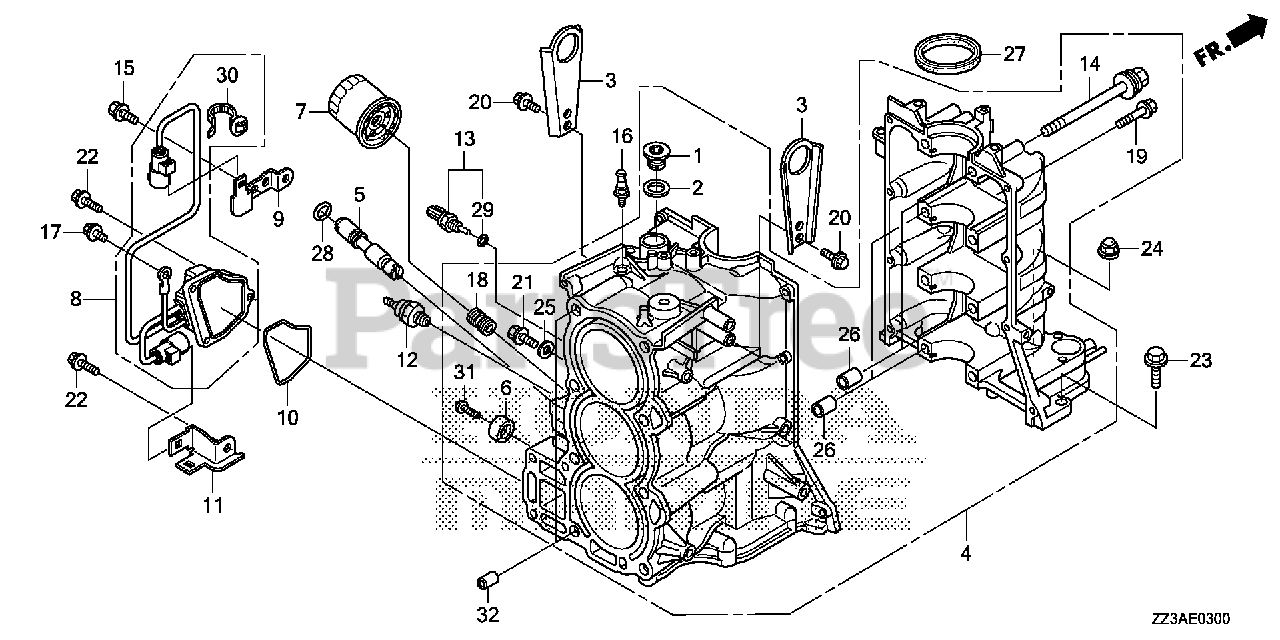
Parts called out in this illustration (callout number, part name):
1	BOLT, SEALING (24MM)
2	WASHER, SEALING (24MM)
3	HANGER, ENGINE
4	BLOCK ASSY., CYLINDER *NH8* (DARK GRAY)
5	BOLT, BLOCK OIL DRAIN
6	METAL, ANODE
7	FILTER, OIL (TOYO ROKI)
8	RECTIFIER ASSY., REGULATOR
9	BRACKET A, REGULATOR CONNECTOR
10	GASKET, REGULATOR
11	BRACKET B, REGULATOR CONNECTOR
12	SWITCH ASSY., OIL PRESSURE
13	SENSOR ASSY., WATER TEMPERATURE
14	BOLT-WASHER (9X100)
15	BOLT, FLANGE (6X14) (CT200)
16	BOLT, TIMING BELT ADJUSTING SPRING
17	BOLT, FLANGE (6X12)
18	HOLDER, OIL FILTER
19	BOLT, FLANGE (6X28)
20	BOLT, FLANGE (6X16)
21	BOLT, FLANGE (6X14)
22	BOLT, FLANGE (6X22)
23	BOLT, FLANGE (8X28)
24	NUT, FLANGE CAP (8MM)
25	WASHER, SEALING (6MM)
26	PIN, DOWEL (12X14)
27	OIL SEAL (52X72X8) (NOK)
28	O-RING (5.1X2.2) (ARAI) (NOT AVAILABLE)
29	O-RING (9.5X1.9)
30	CLIP, HARNESS BAND (145MM) (BLACK)
31	SCREW, PAN (6X18)
32	PIN, DOWEL (14X20)
